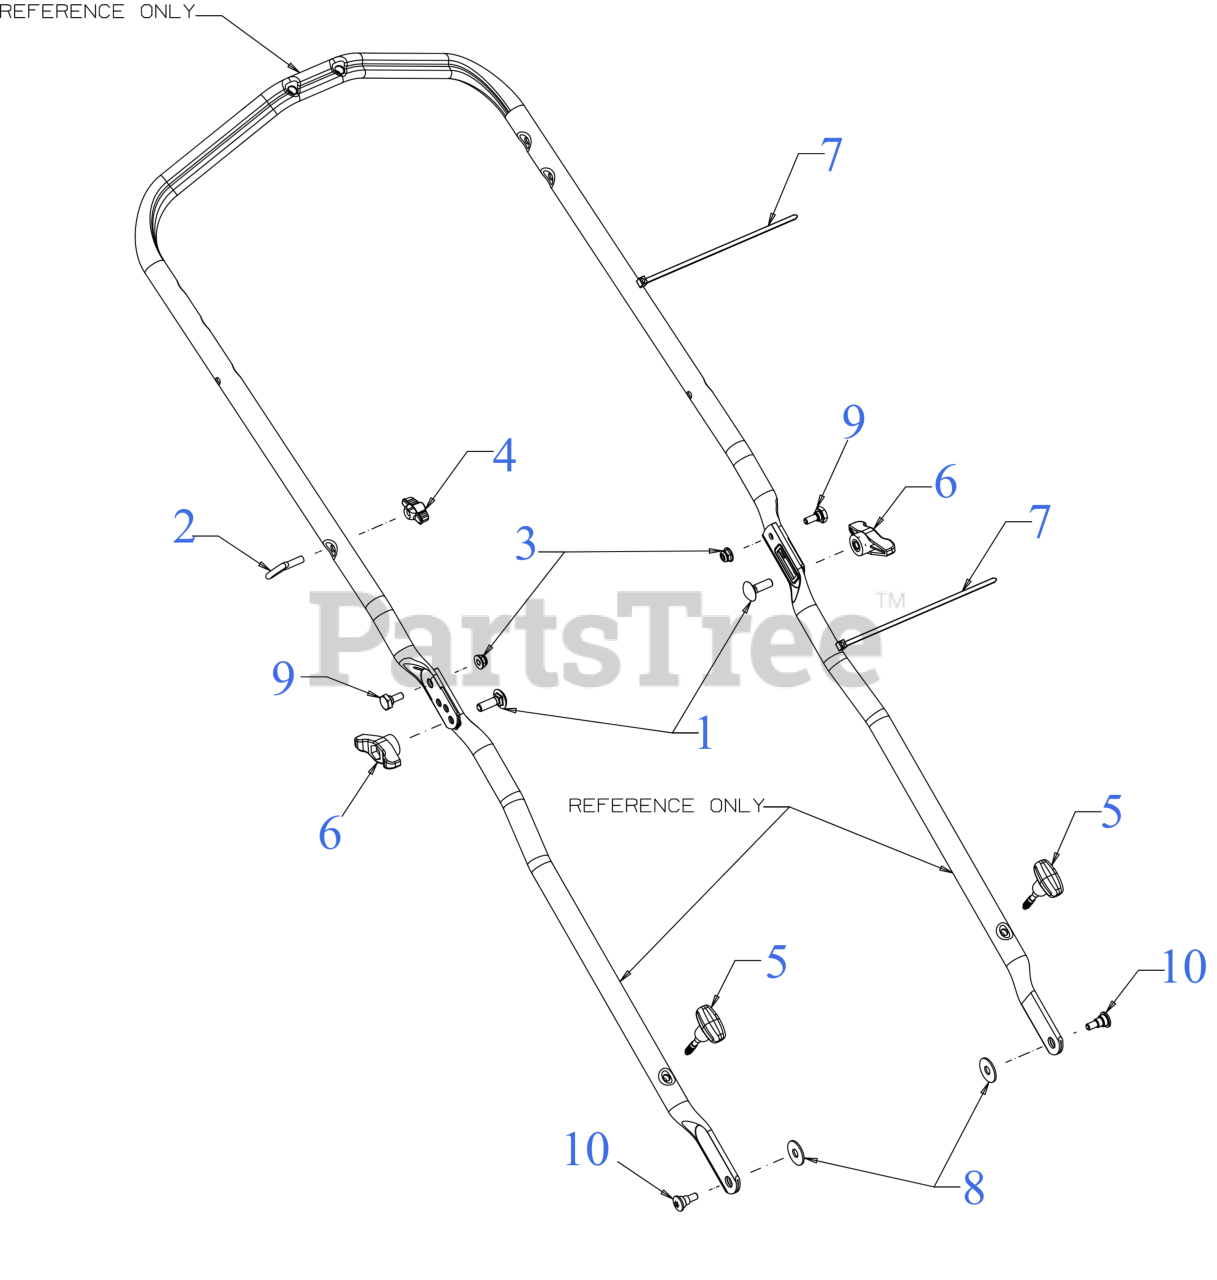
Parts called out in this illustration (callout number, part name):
1	SCREW 5/16-18 x 1.00 GR5
2	EYEBOLT 1/4-20
3	FLANGE LOCK NUT
4	HANDLE KNOB
5	WING KNOB 1/4-20 x 1.80
6	WING KNOB 5/16-18
7	7" CABLE TIE
8	FLAT WASHER 344X1.00
9	SHOULDER SCREW
10	SHOULDER SCREW .450X .188X 1/4-20
